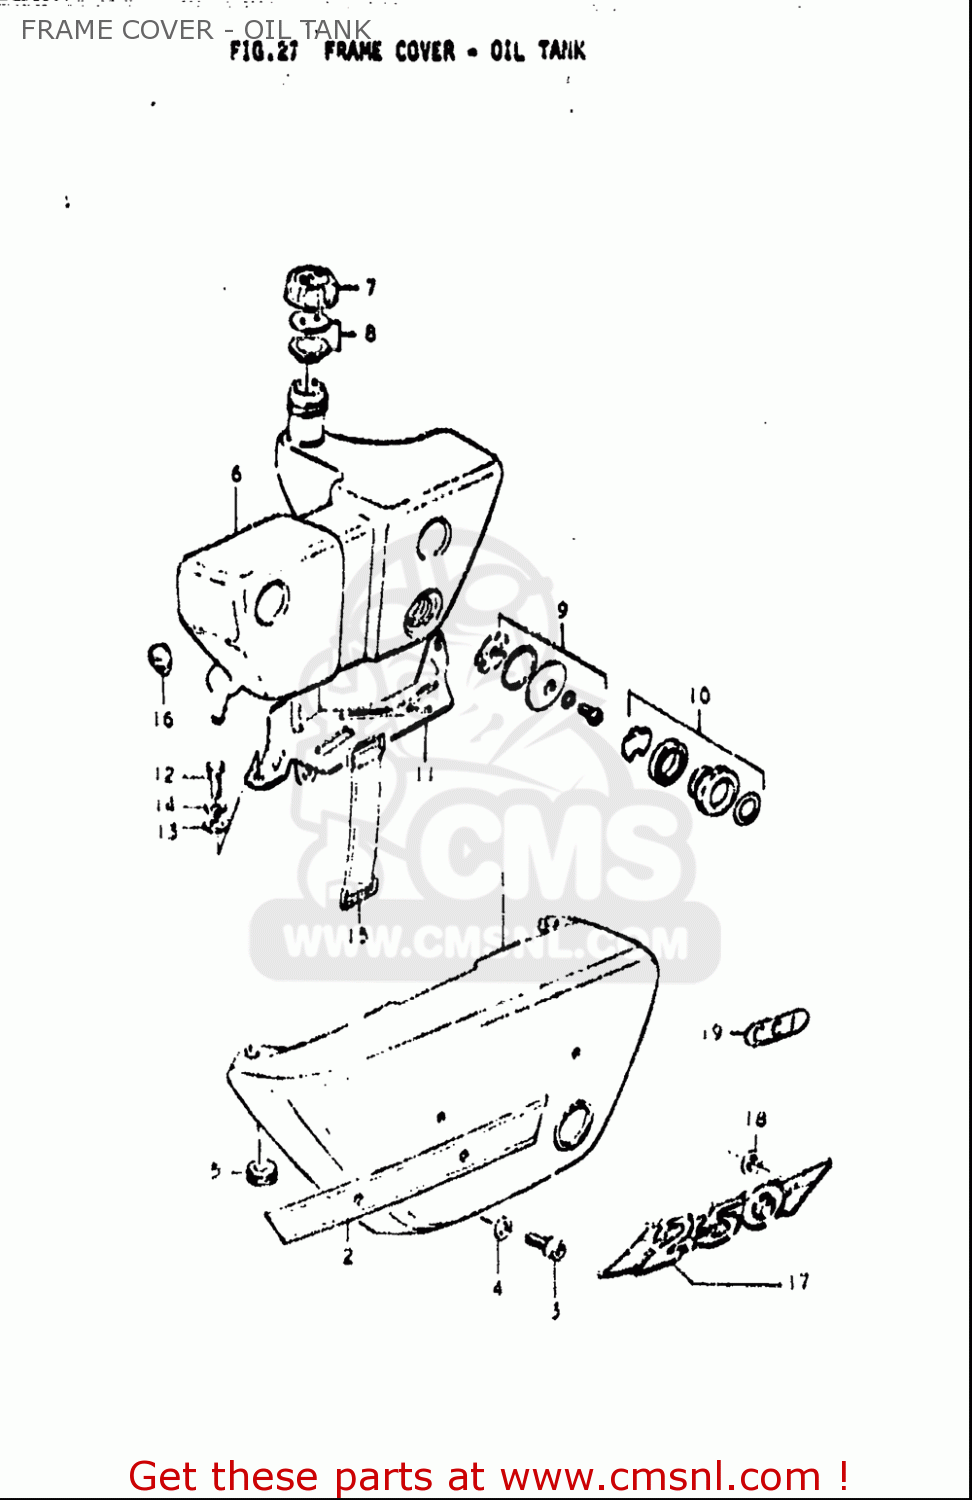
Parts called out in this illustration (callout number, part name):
2	TAPE,FRAME COVER
3	SCREW(6X12)
4	WASHER
5	CUSHION
7	CAP,OIL TANK
8	GASKET SET (NAS)
10	LENS SET,OIL LEVEL
12	BOLT
13	WASHER
14	WASHER,LOCK
15	BAND
16	CUSHION
18	NUT
19	EMBLEM,CCIS
